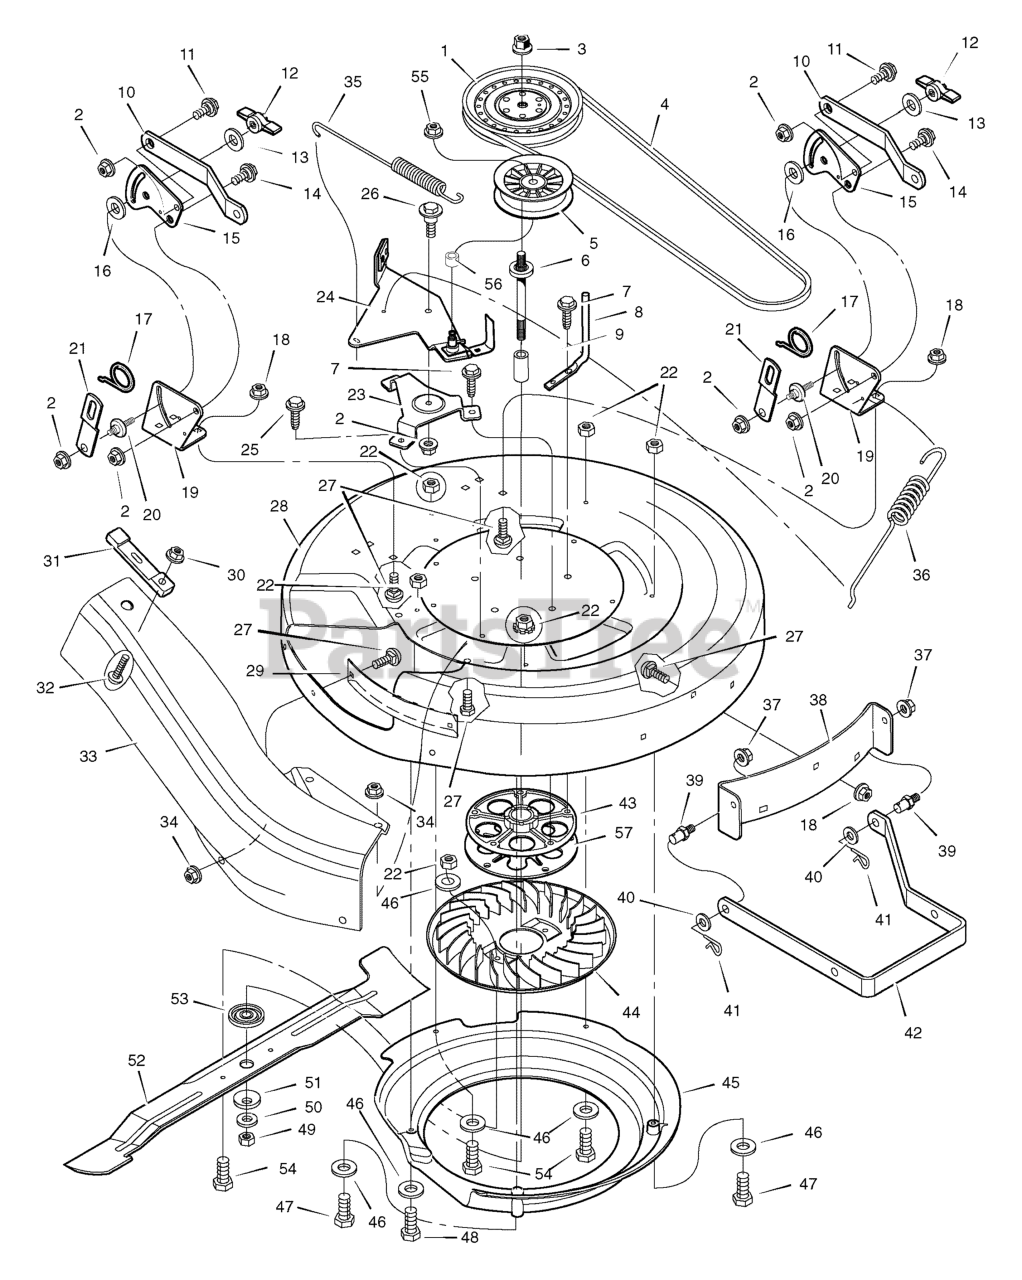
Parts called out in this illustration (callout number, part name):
2	NUT, Flange
4	BELT, Blade
5	PULLEY, Idler
6	MANDREL
8	GUIDE, Belt
10	BRACKET, Rear Suspension
11	BOLT, Shoulder
12	KNOB
14	BOLT, Shoulder
15	Plate, Suspension
16	PAD, Friction
18	NUT, Flange
19	BRACKET, Rear Deck
20	PIN, Hanger
21	LINK, Lift
22	NUT
23	BRACKET, Idler Arm
24	ASSEMBLY, Idler Arm & Pad
26	BOLT, Shoulder
27	BOLT, Carriage
28	HOUSING, Blade
29	BAFFLE, Deck, RH
30	NUT, Flange
31	STRAP, Rubber
32	SCREW
34	NUT
35	SPRING, PTO
36	SPRING, Extension
37	NUT, Flange
38	BRACKET, Front Deck
39	PIN, Threaded Shoulder
41	PIN, Hair
42	HANGER, Front
43	HOUSING, Jackshaft
44	FAN, Assist
45	HOUSING, Fan
46	WASHER
47	BOLT
48	BOLT
51	WASHER, Belleville
53	ADAPTER, Blade
54	BOLT
55	NUT, Flange
57	PLATE, Jackshaft Support
